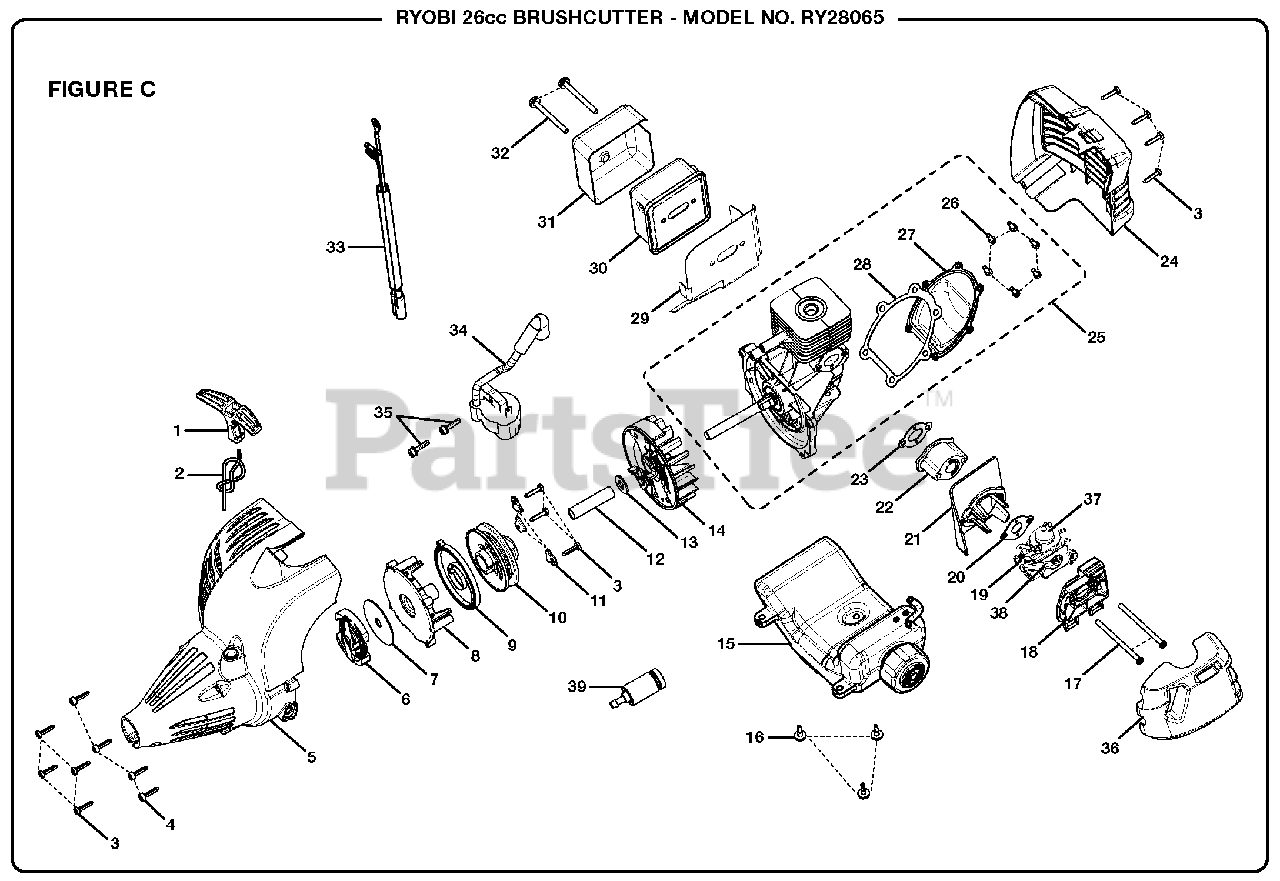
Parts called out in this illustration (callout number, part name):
1	Starter Grip
2	Starter Rope (42 in.)
3	Screw (M4 x 18 mm)
4	Screw (M4 x 16 mm)
5	Starter Housing Assembly
6	Clutch Assembly
8	Starter Baffle
9	Spring and Container
10	Easy Starter Assembly
11	Pulley Retainer
12	Spacer Tube
13	Washer
14	Flywheel Assembly
15	Fuel Tank and Cap Assembly
16	Screw (M4)
17	Bolt (M5 x 70 mm)
18	Air Box Base
19	Carburetor Assembly
20	Outer Heat Dam Gasket
21	Air Baffle
23	Inner Heat Dam Gasket
24	Rear Housing
25	Short Block Assembly
26	Screw (M4 x 12 mm)
27	Crankcase Cover
28	Crankcase Cover Gasket
29	Muffler Gasket
30	Muffler Assembly
31	Muffler Housing
32	Muffler Bolt (10-24 x 2-1/8 in.)
33	Electrical Lead Wire Assembly
34	Ignition Module
35	Screw (M4 x 19 mm)
36	Air Box Cover
37	Primer Bulb (Ruixing)
38	Choke Lever (Ruixing)
39	Fuel Filter
